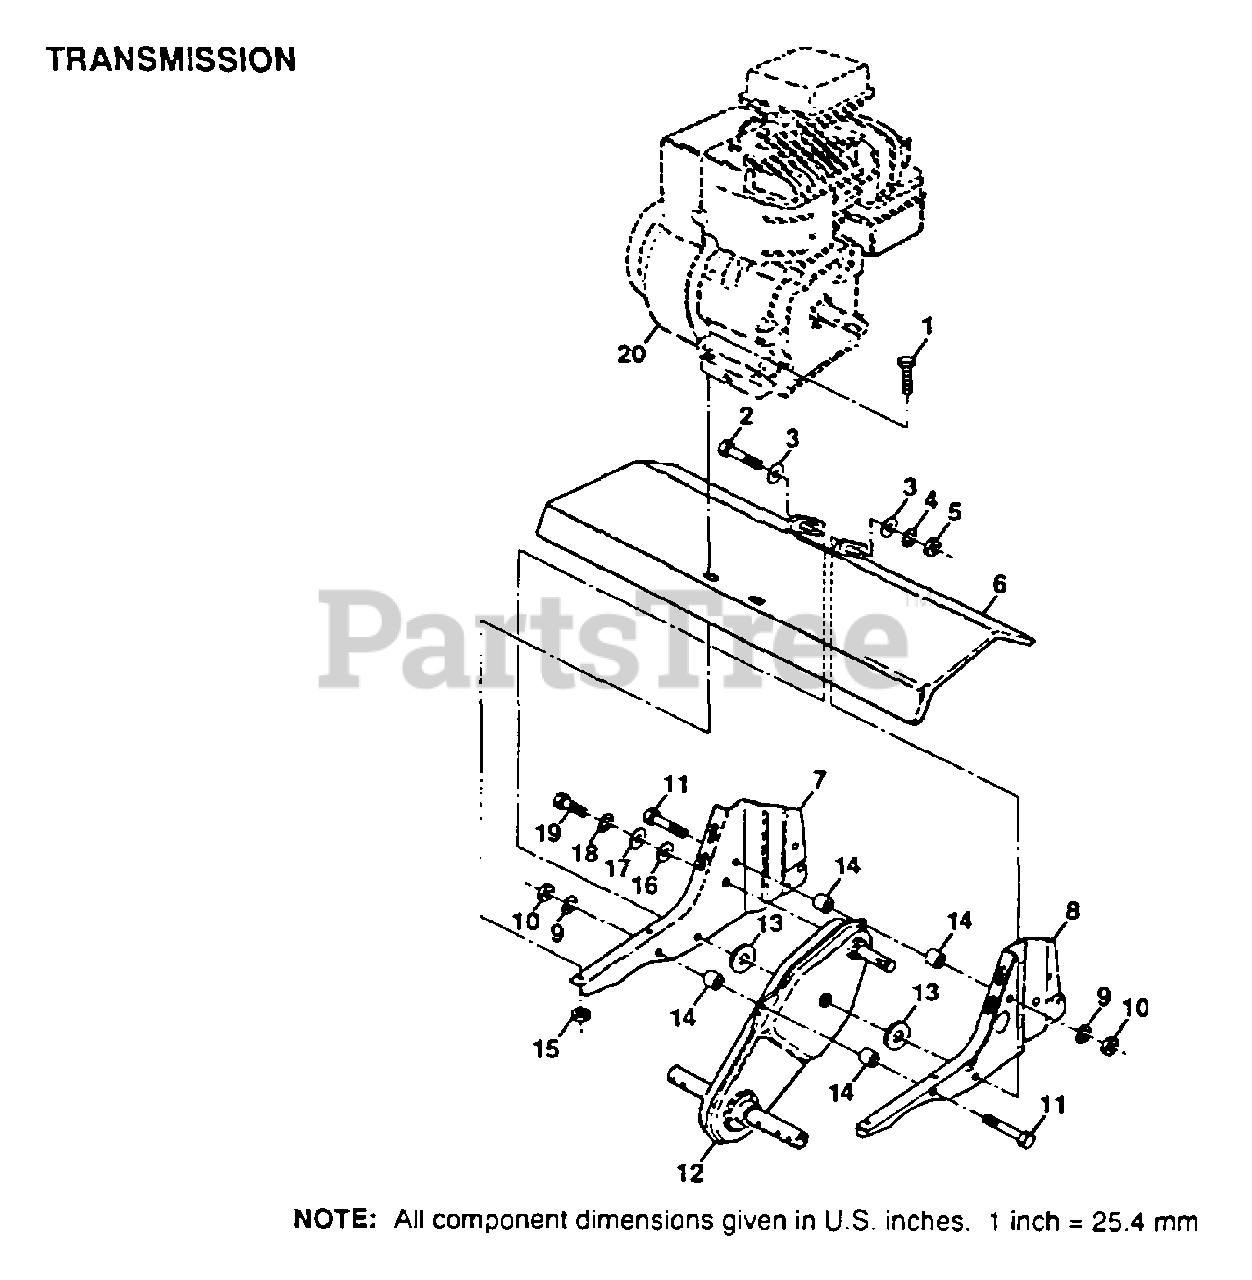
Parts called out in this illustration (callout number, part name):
1	BOLT.HEX.5/16-1.5
2	BOLT.3/8-24X3.75
3	WASHER
4	LOCKWASHER
5	GRIPCO NUT
6	"SHIELD, TINE"
8	BRACKET.ENG.LH.
9	LOCKWASHER
10	NUT.HEX.5/16-18
14	SPLIT SPACER RT
16	WASHER
17	WASHER
18	LOCKWASHER
19	BOLT
